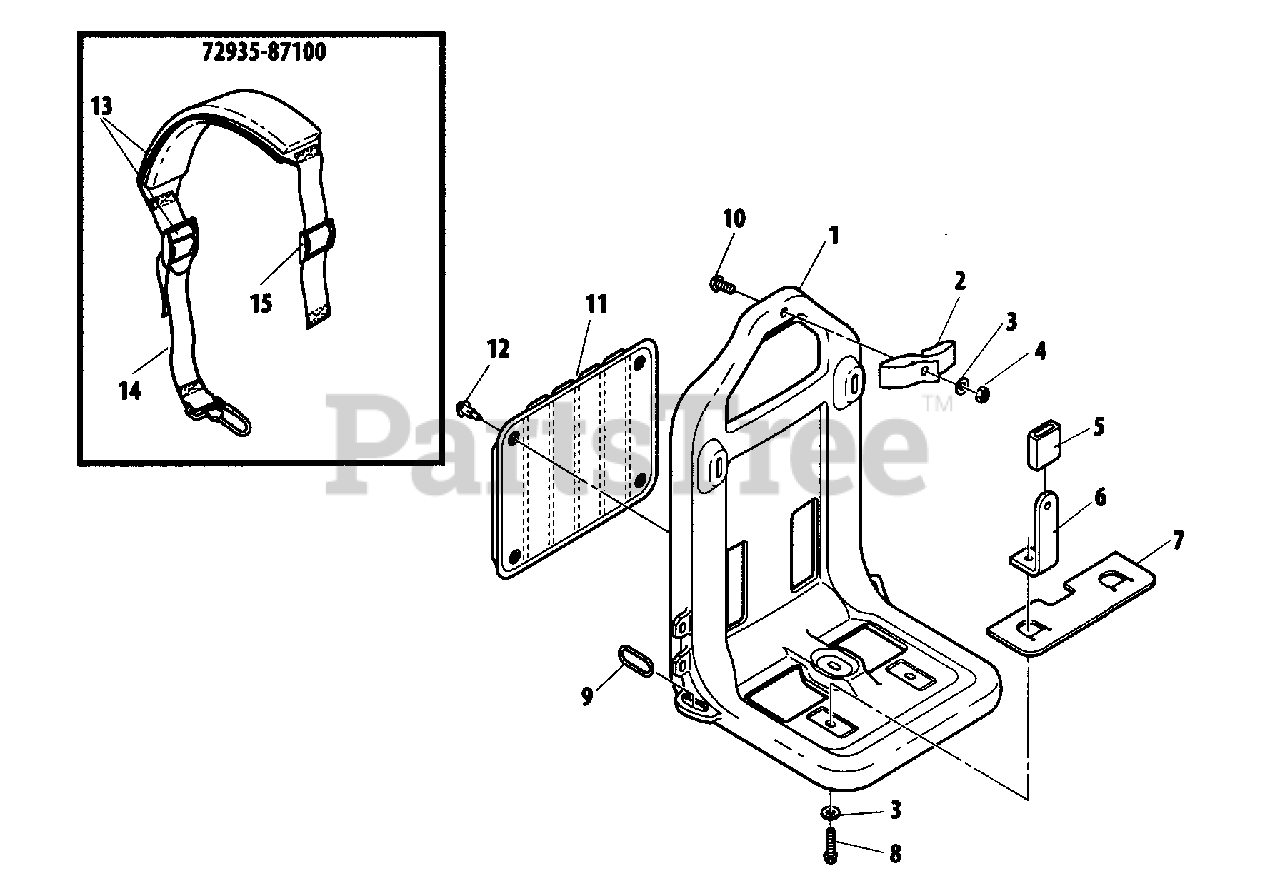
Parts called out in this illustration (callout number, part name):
1	FRAME, BACKPACK
2	HANGER, HARNESS
3	COLLAR Ø18ר6.4×L2
4	NUT, LOCK M6
5	CUSHION
6	BRACKET
7	CUSHION
8	BOLT M6×20
9	RING, HARNESS
10	SCREW, TRUSS M6×30
11	PAD, BACKPACK
12	CLIP
13	HARNESS
14	STRAP, HARNESS
15	BUCKLE
72935-87100	HARNESS ASSY
